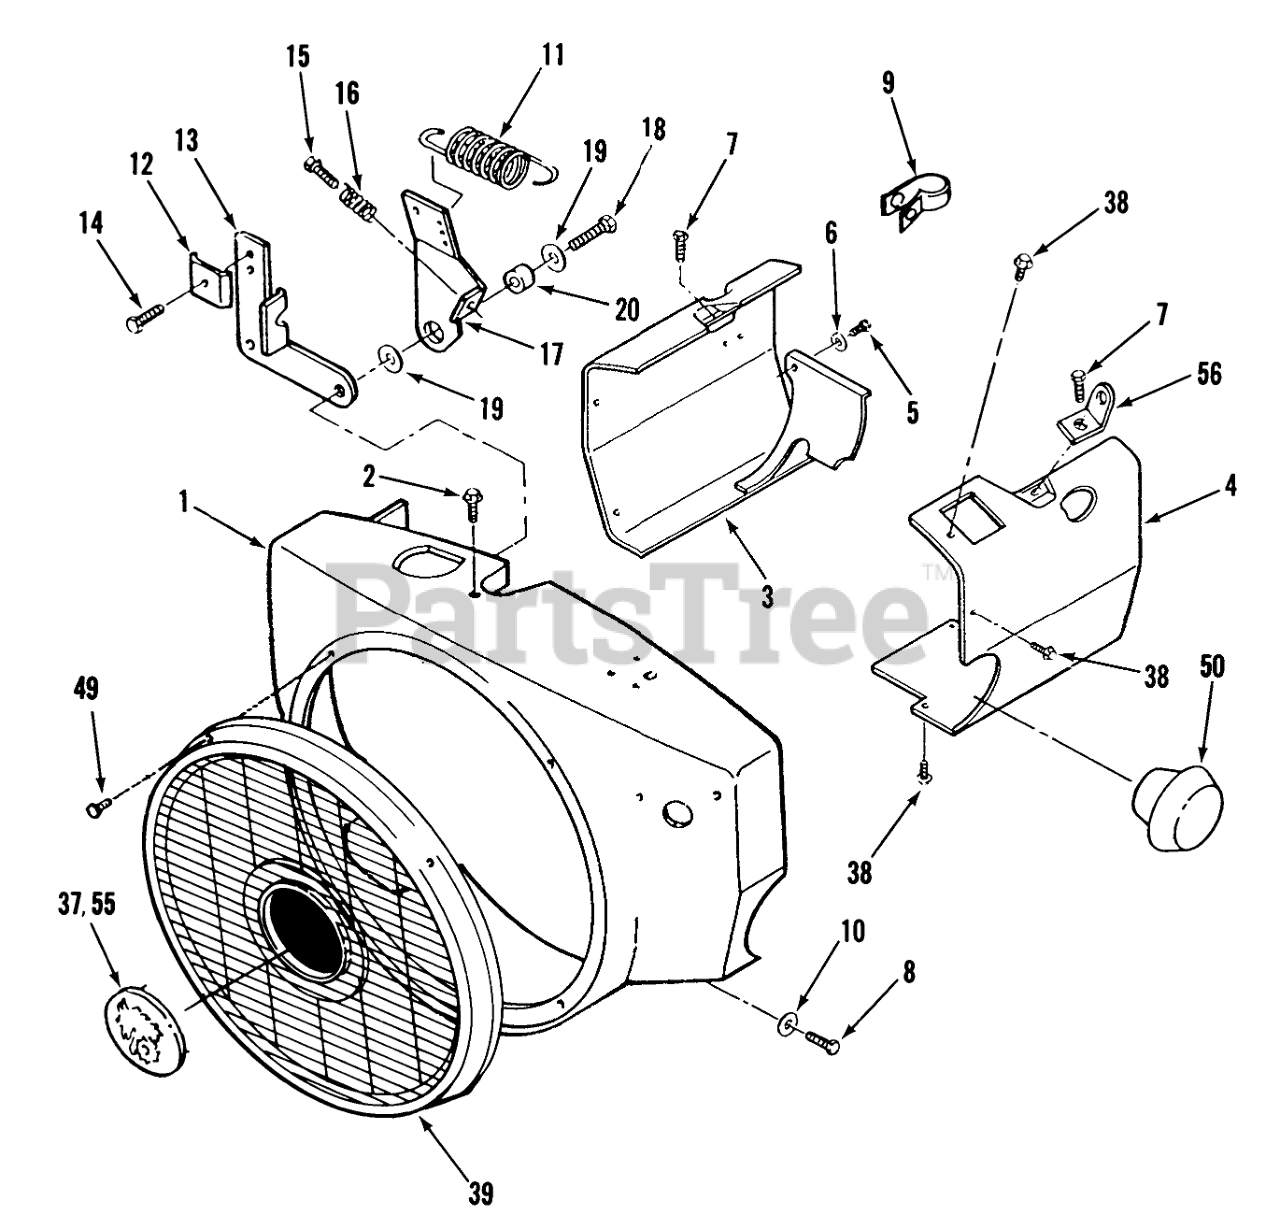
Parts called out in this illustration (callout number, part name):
1	Blower Housing
2	Bolt
3	CYLINDER AIR HSG L H
4	Cylinder Air Housing
5	Bolt
6	Screw
7	Bolt
8	Bolt
9	Clamp
10	Washer
11	Spring
12	Clip
13	Bracket
14	Bolt
15	Bolt
16	Spring
17	Governor Control Arm w/o Swivel
18	Bolt
19	Screw
20	Bushing
37	Plug
38	Bolt
39	Stationary Guard
49	Screw 1/4-20 x 3/8
50	Hole Plug
55	NAME PLATE LOGO
56	Bracket-Lifting
